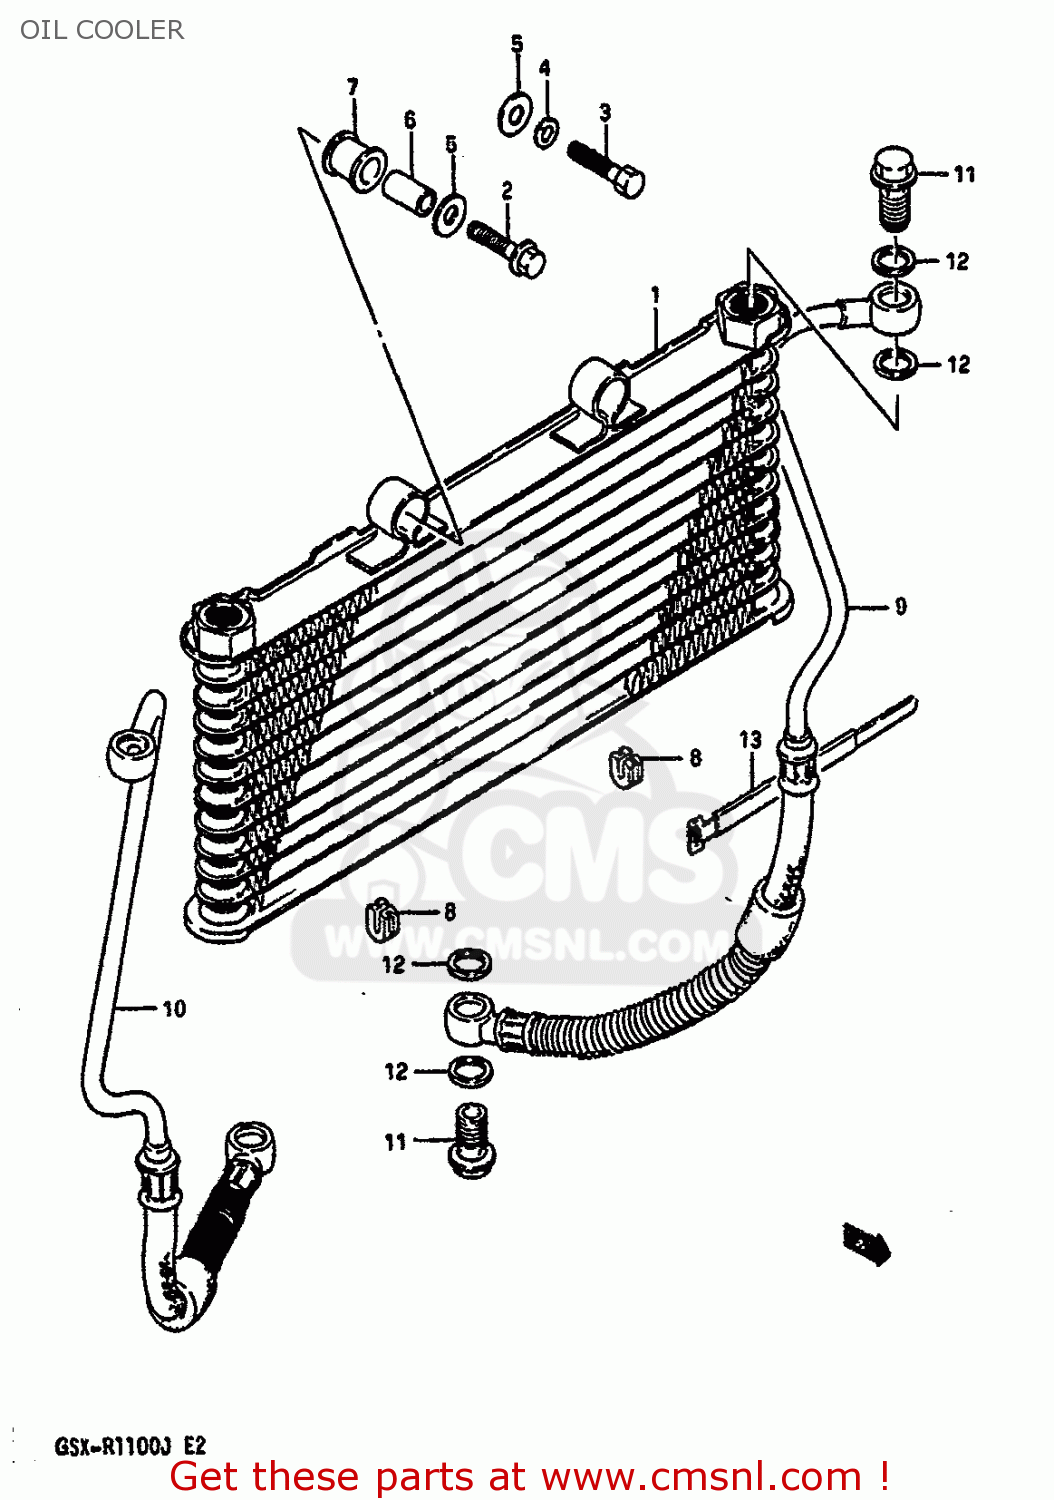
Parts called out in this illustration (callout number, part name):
1	COOLER ASSEMBLY,OIL
2	BOLT 8X40
3	BOLT 8X40
4	WASHER,LOCK,8.
5	WASHER(8.5X23X1.2)
6	SPACER (8.8X12X24.5)
7	CUSHION,OIL COOLER NO.1
8	CUSHION,OIL COOLER NO.2
9	HOSE,OIL COOLER,L
10	HOSE,OIL COOLER,RIGHT
11	BOLT UNION
12	GASKET(16X22X2) (NAS)
13	CLAMP
